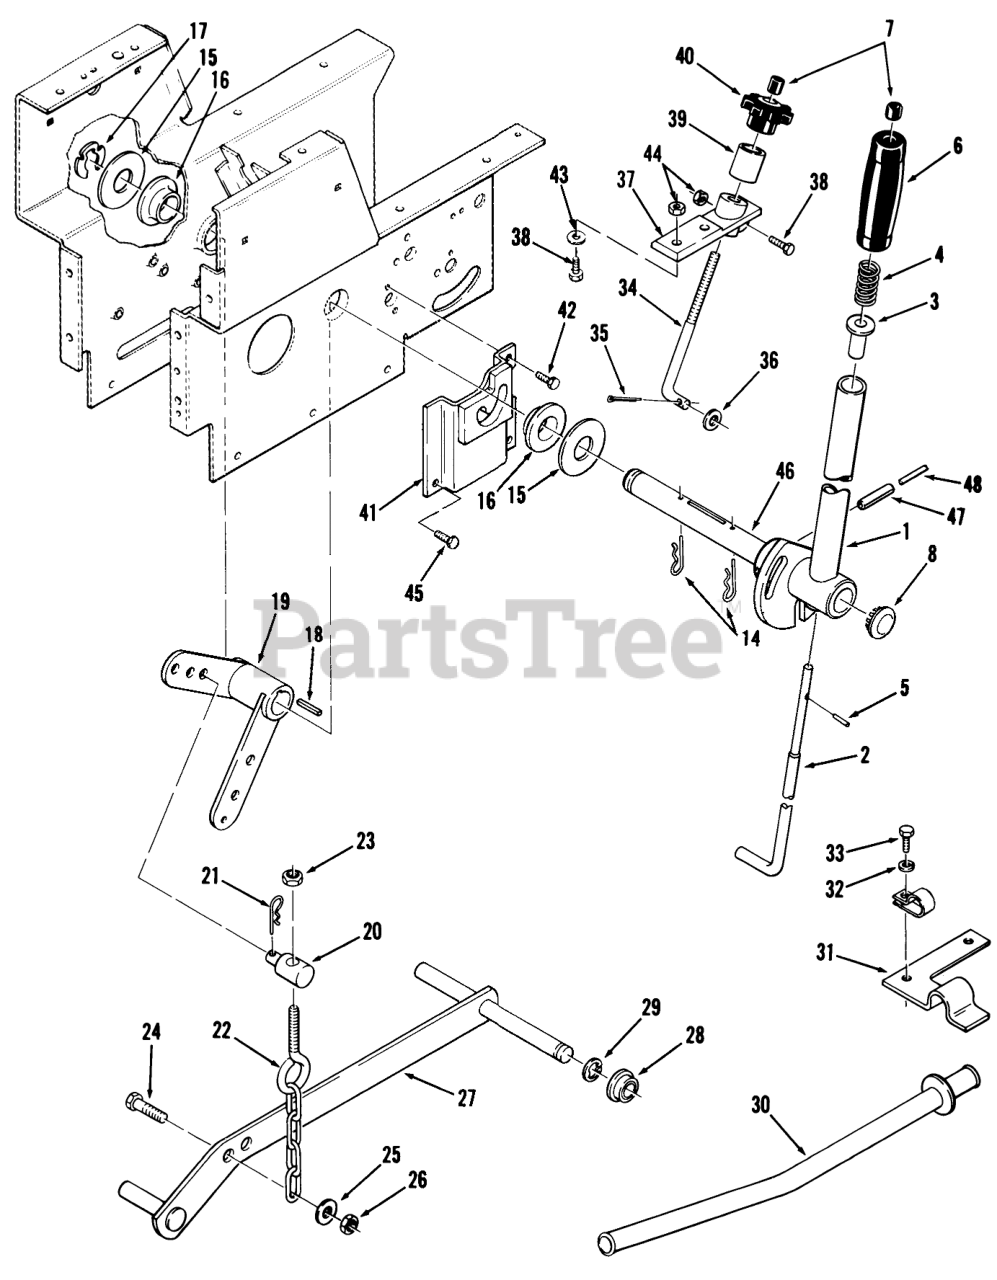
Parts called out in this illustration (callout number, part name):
1	Lift Lever
2	ROD-LATCH LIFT
3	RETAINER-SPRING
4	SPRING-COMPRESSION
5	PIN-SPIROL
6	HANDGRIP
7	CAP-ROD, PLUNGER
8	PLUG
14	Pin-Cotter
15	WASHER
16	BEARING-FLANGE
17	Retainer
18	KEY-SQUARE
19	Bellcrank
20	TRUNNION-LIFT
21	Hairpin
22	CHAIN-LIFT
23	Nut
24	Bolt
25	WASHER 5/16 SAE
26	Nut
27	ASSY LIFT BAR R
28	BUSHING
29	E Ring
30	TUBE ASSY COMPLET R
31	Clamp-Tube
32	LOCKWASHER
33	Bolt
34	Rod
35	Pop Rivet
36	WASHER -4
37	Casting
38	Bolt
39	Sleeve
40	KNOB-LIFT CONTROL
41	Latch Bracket
42	SCREW
43	WASHER 5/16 SAE
44	Nut
45	Bolt
46	SHAFT-LIFT LEVER
47	SPIROL PIN
48	Roll Pin
